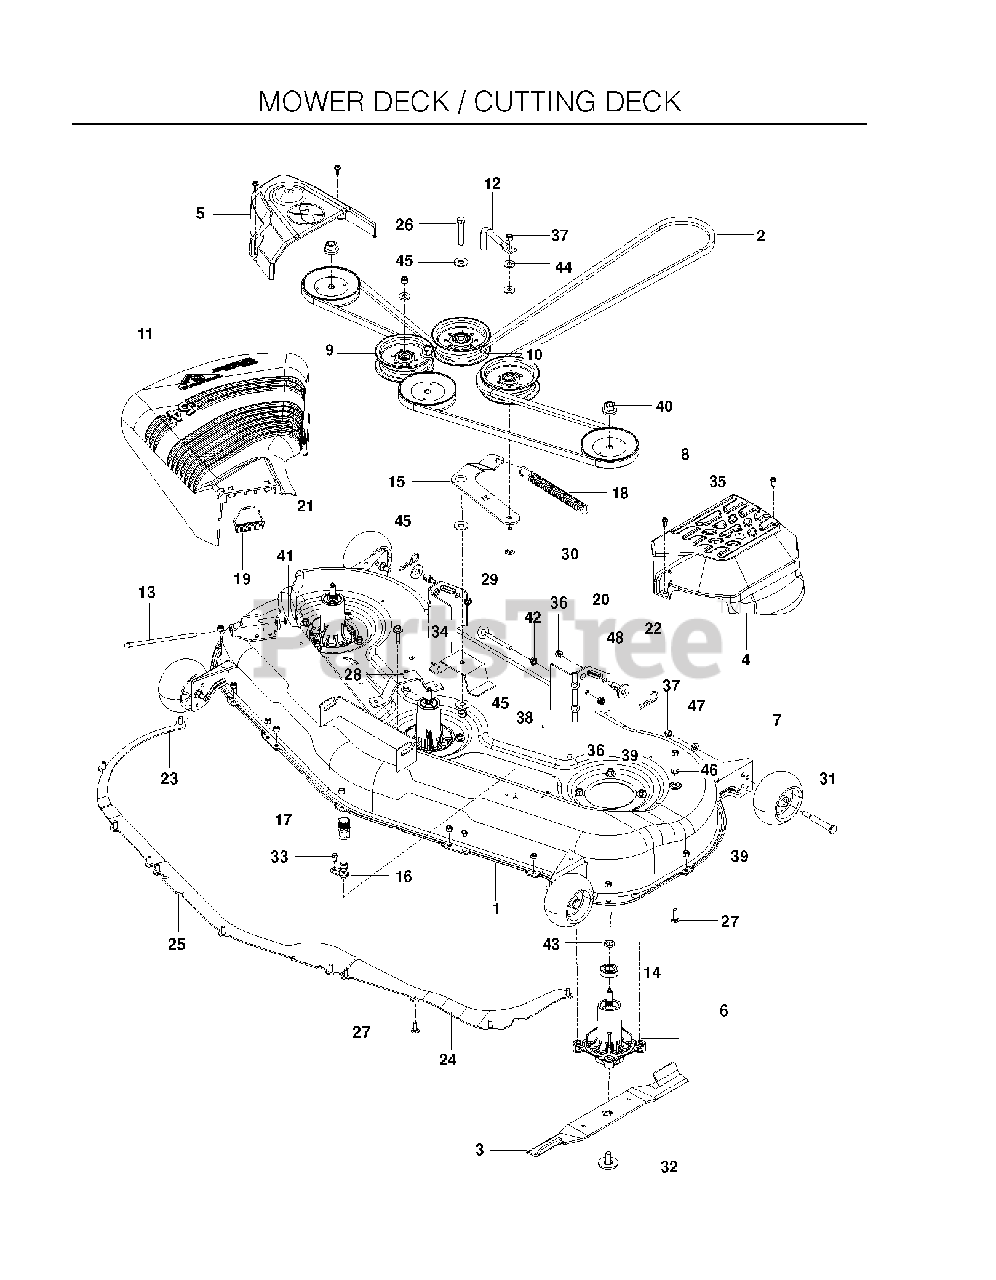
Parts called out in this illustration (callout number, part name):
1	DECK W/DECALS - SZ54
2	BELT-DECK, 52
3	BLADE, BAGGING 54"
4	COVER.MANDREL.LH.DECK.54"
5	COVER.MANDREL.RH.DECK.54"
9	PULLEY.IDLER.2006
10	PULLEY.IDLER.MWR.STATI
12	BELT KEEPER 5"
14	BEARING, BALL
15	ARM, IDLER, BLACK
16	PORT.WASHOUT
17	COUPLING.QUICK CONNECT
18	SPRING, DECK BELT
19	TORSION SPRING
20	STUD.FASTNER.W/ANTI-ROTATE
22	HAIRPIN #4
26	BOLT 7/16-14 X 2-1/2 GR 5 ZD
27	BOLT 5/16C X 3/4" CARRIAGE
28	RHSNB 3/8C X 2
29	EYE BOLT 5/16 X 3.50
30	CARRIAGE BOLT 3/8-16 X
31	SHOULDER BOLT 1/2X2-5/8 ZD SPE
33	BOLT 1/4-20 X 1/2 HWST
35	SCREW- 1/4-20 X 5/8
36	5/16-18 NYLOC FLANGE NUT
37	NUT 3/8-16 NYLOC
38	7/16-14 HEX NUT W/NYL RING ZD
39	NUT 5/16 NYLOC
42	NUT 5/16C WHIZ
43	WASHER.SPACER.MANDREL
44	WASHER 3/8 FLAT
45	WASHER 7/16 FLAT ZD
46	FLAT WASHER 5/16 SAE
47	WASHER 3/8 SAE FLAT
48	WASH USS FLAT 1/2
